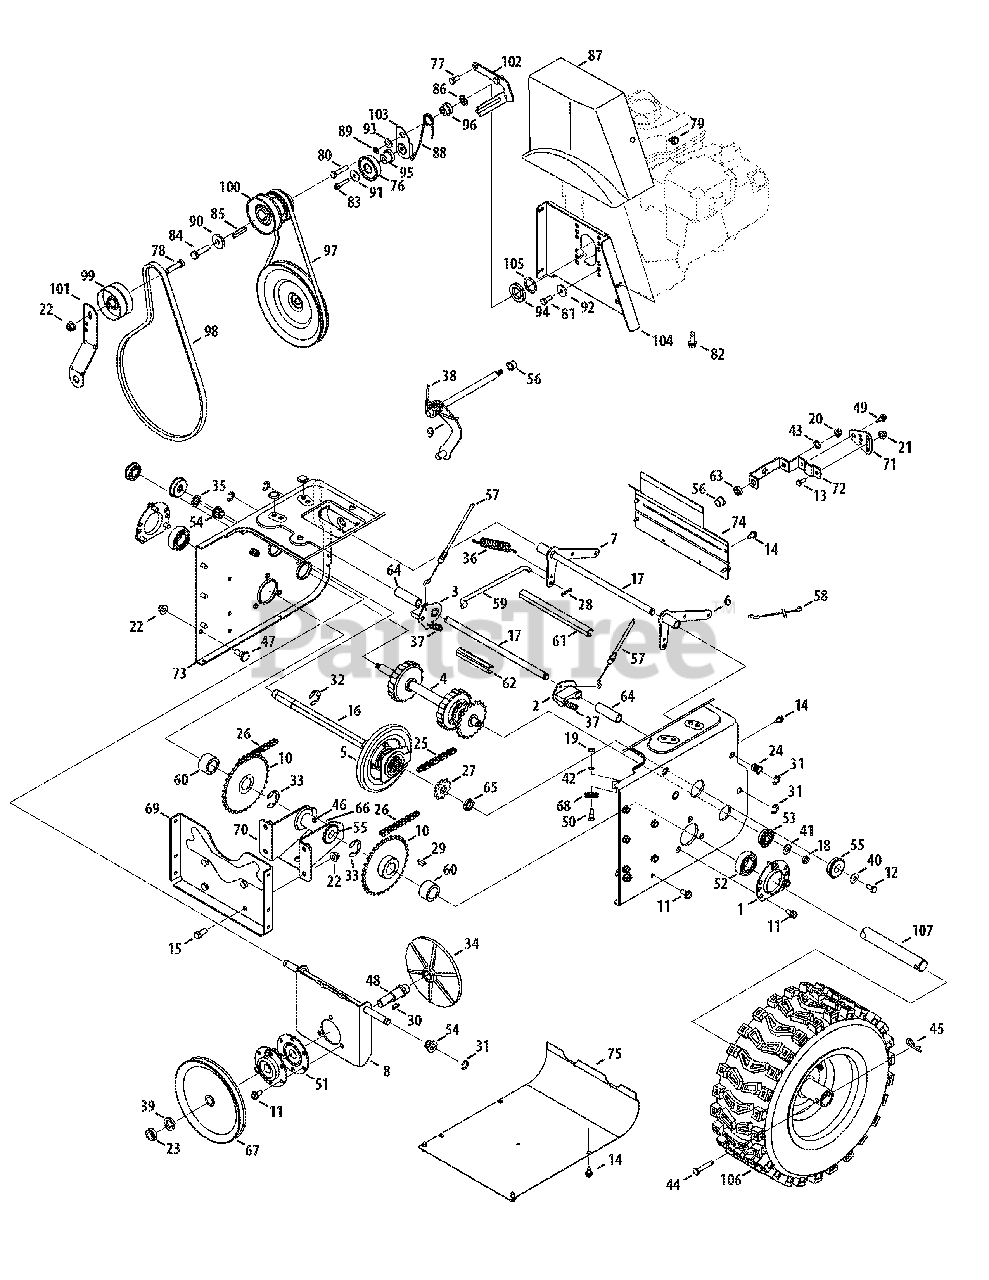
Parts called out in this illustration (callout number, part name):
1	Housing, Bearing
2	Dogg, Steering Drive, LH
3	Dogg, Steering Drive, RH
4	Shaft Assembly, Steering
5	Assembly, Friction Wheel
5	Wheel, Friction, Bonded
5	Screw, Hex Wash
9	Arm, Shift
10	Sprocket, 32T
11	TT Screw, 5/16-18 x .750
12	Screw, Hex Cap Lk, 5/16-18 x .625 Gr5
13	Screw, Hex, 1/4-20 x .620
14	Screw, Hex Wash.
15	Screw, Hex Cap, 3/8-16
16	Shaft, Hex Drive
17	Shaft, Actuator
18	Nut, Hex Insert Jam Lock
19	Nut, Hex, 1/4-28 GR5
20	Nut, Hx Flnge Insert Lk, 5/16-18 GrF
21	Nut, Hx Flnge Insert Lk, 1/4-20 GrF
22	Nut, Hx Flnge Insert Lk
23	Nut, Hx Insert Jam Lk
24	Nut, Insert 3/8-16
25	Chain, Endless, #41 x 36L
26	Chain, #420 x 40L
27	Sprocket, #41 x 10T
28	Pin, Internal Cotter
29	Key, Woodru
30	Key, Hi-Pro, 3/16 x 5/8
31	E-Ring
32	Ring, Retaining
33	Ring, Retainer
34	Plate, Drive
35	Nut, Speed
36	Spring, Extension
37	Spring, Extension
38	Spring, Torsion
39	Washer, Lock, 5/8
40	Washer, Belleville, .34 x .872 x .06
41	Wash, .406 x .875 x .059
42	Washer, Lock, 1/4
43	Washer, Flat, .469 x .875 x .105
44	Pin, Clevis
45	Pin, Internal Cotter
46	Fitting, Lube, 3/16 Drive
47	Screw, Shldr., .498 x .34
48	Spindle, Drive Plate
49	Screw, Shoulder, .368 x .113:1/4-20 TT
50	Screw, Hex Shldr., 1/4-28
51	Ass’y, Bearing/Housing
52	Bearing, Self Aligning
53	Bearing, Ball
54	Bearing, Hex Flange
55	Bearing, Ball
56	Bush, Flg, .5 ID x .627 OD
57	Cable, Steering
58	Cable, Auger Idler
59	Rod, Drive Clutch
60	Spcr., 1.0 ID x 1.50 OD
61	Spcr., .51 ID x 7.895 Lg.
62	Spcr., .51 ID x 3.66 Lg.
63	Spacer, .5151 x .75 x .22
64	Spcr., .514 x .632 x 2.44
65	Spacer, .675 x 1.0 x .23
66	Spcr, .6725 x 1.125 x 2.48
67	Pulley, Drive
68	Roller, Cable
76	Pulley, Flat Idler, 3.0 OD
77	Screw, Hex Cap, 5/16-24 x .625 Gr5
78	Screw, Hex Cap, 3/8-16 x 1.75
79	Screw, Hex Tapp, 5/16-18 x .50
80	Screw, Hex Cap, 5/16-24 x 1.50
81	Screw, Hex Cap, 5/16-24 x .75
82	Screw, Hex Sems Tapp, 3/8-16 x 1.0
83	Screw, Hex Tapp, 1/4-20 x 1.25
84	Screw, Hex Cap, 3/8-24 x 1.50
85	Key, Square, 1/4 x 1.5
86	Push Nut, .25 dia.
87	Cover, Belt
88	Torsion Spring
89	Lock Washer 5/16
90	Washer, Flat, .406 x 1.25 x .157 Ht.
91	Washer, Flat, .265 x 1.0 x .030
92	Spacer, Shoulder
93	Shoulder Spacer, .3175 x .500 x .0975
94	Spacer, 1.004 x 1.375 x .25
95	Shoulder Spacer, .260 x .785 x .538
96	Shoulder Spacer, .340 x 1.00
97	V-Belt, 3/8 x 34.4
98	V-Belt, 1/2 x 42.0
99	Idler, Flat, 2.75 OD
100	Pulley, Double, 3.25 OD
101	Auger Idler Bracket
103	Bracket, Idler, Drive
105	Flat Washer, 1.015x1.375x.062
107	Axle, Wheel
